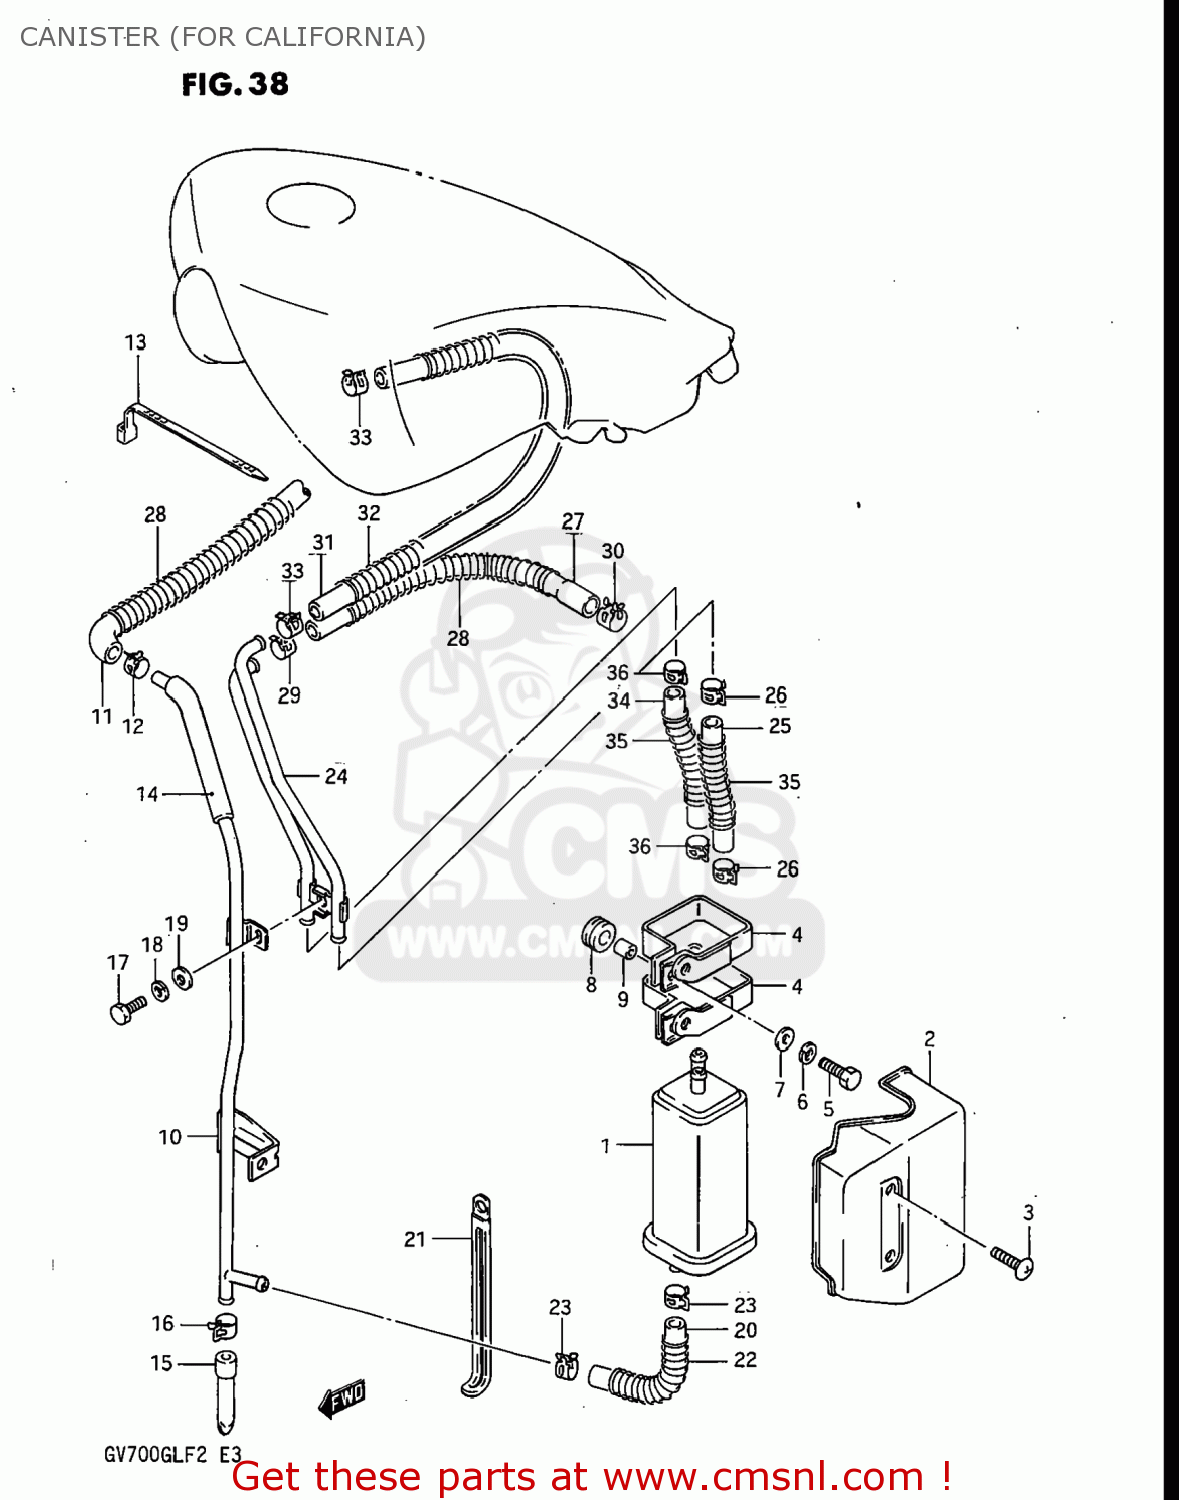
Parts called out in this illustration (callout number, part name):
1	(CA) CANISTER ASSEMBLY
3	SCREW
5	BOLT
6	LOCK WASHER
7	WASHER
8	CUSHION
9	SPACER(6.1X9X7.5)
10	(CA) PIPE,CANISTER DRAIN L
11	HOSE
12	(CA) CLIP
13	CLAMP(L:125)
14	HOSE
15	(CA) CAP,CANISTER DRAIN
16	(CA) CLIP
17	BOLT
18	LOCK WASHER
19	WASHER
20	HOSE
21	CLAMP
22	(CA) SPRING
23	CLAMP
24	PIPE
25	HOSE
26	(CA) CLIP
27	HOSE
28	(CA) SPRING
29	(CA) CLIP
30	CLAMP
31	HOSE
32	(CA) SPRING
33	(CA) CLIP
34	HOSE
35	SPRING
36	(CA) CLIP
